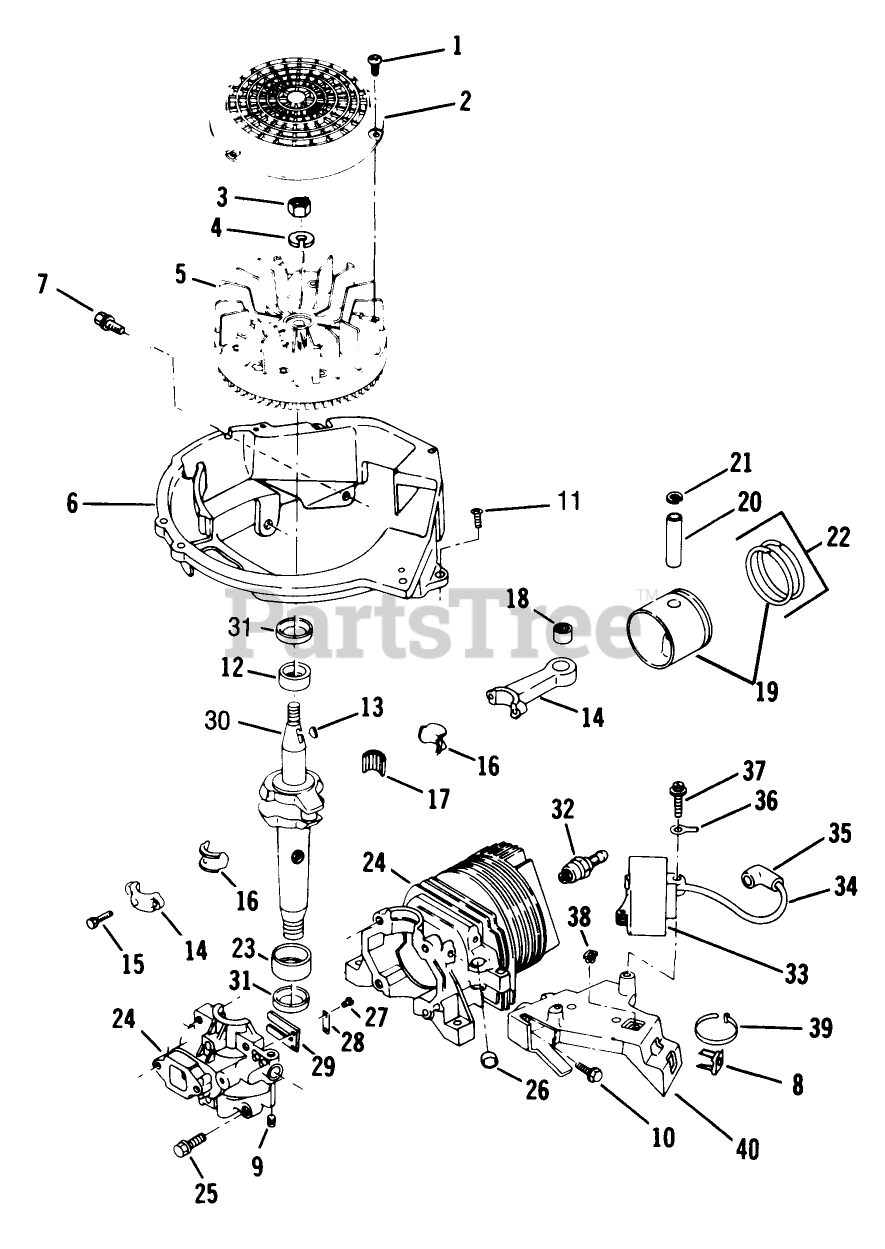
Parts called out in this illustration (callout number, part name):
1	SCREW F
2	SCREEN F'WHEEL S
3	NUT
5	FLYWHEEL ASSY F
7	SCREW-SEMS
8	NUT-CLIP
11	SCREW F
12	BEARING V
13	KEY
15	SCREW-HSH
16	LINER ASM
17	BEARING-NEEDLE
18	BEARING AY F
21	RING-RETAINING
23	BEARING V
25	SCREW S
26	PLUG-CORE VF
27	SCREW-HH
28	PLATE-BACKUP, REED
31	SEAL-OIL
34	HT LEAD&COVER XEV
36	TERMINAL S
38	NUT-CLIP
